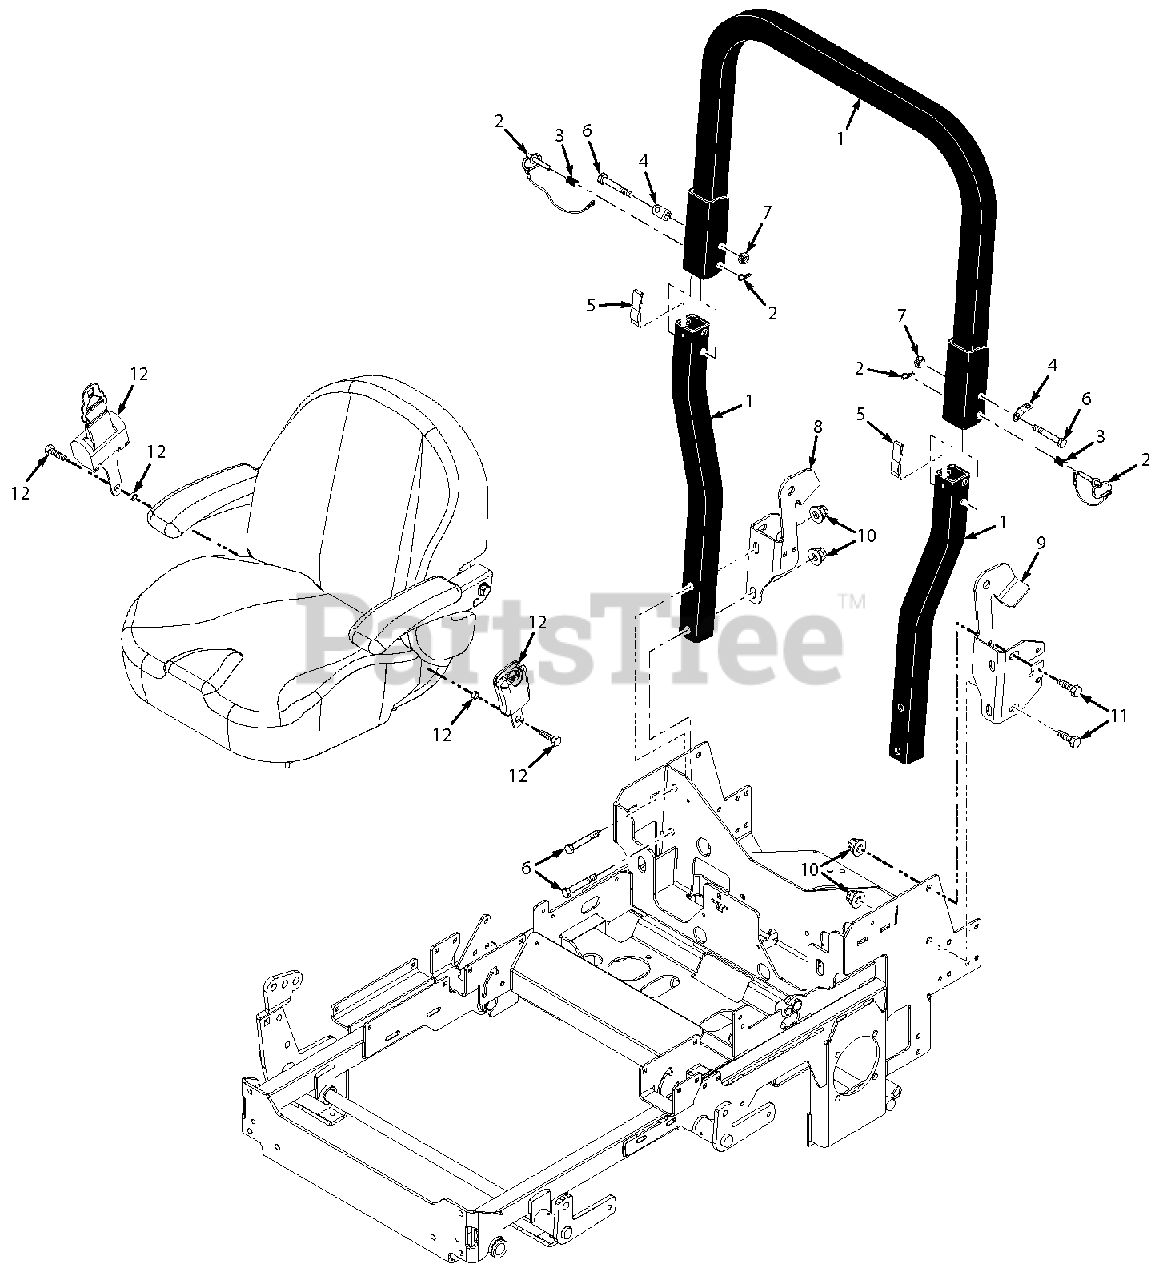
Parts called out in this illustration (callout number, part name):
1	ROPS Assembly, Foldable
2	Pin Assembly
3	Spring, ROPS
4	Clip, ROPS
5	Spring, ROPS Anti-Rattle
6	Bolt, Hex Head 1/2-13 x 3-1/4"
7	Nut, Elastic Stop 1/2-13
8	ROPS Mount, RH
8	ROPS Mount, RH, 29CV-EFI
9	ROPS Mount, LH
9	ROPS Mount, LH, 29CV-EFI
10	Nut, 1/2-13 Flange Elastic Stop
11	Bolt, Hex Head 1/2-13 x 1-1/4"
12	Seat Belt Kit (Suspension Seat)
12	Seat Belt Kit (Soft Ride Seat)
